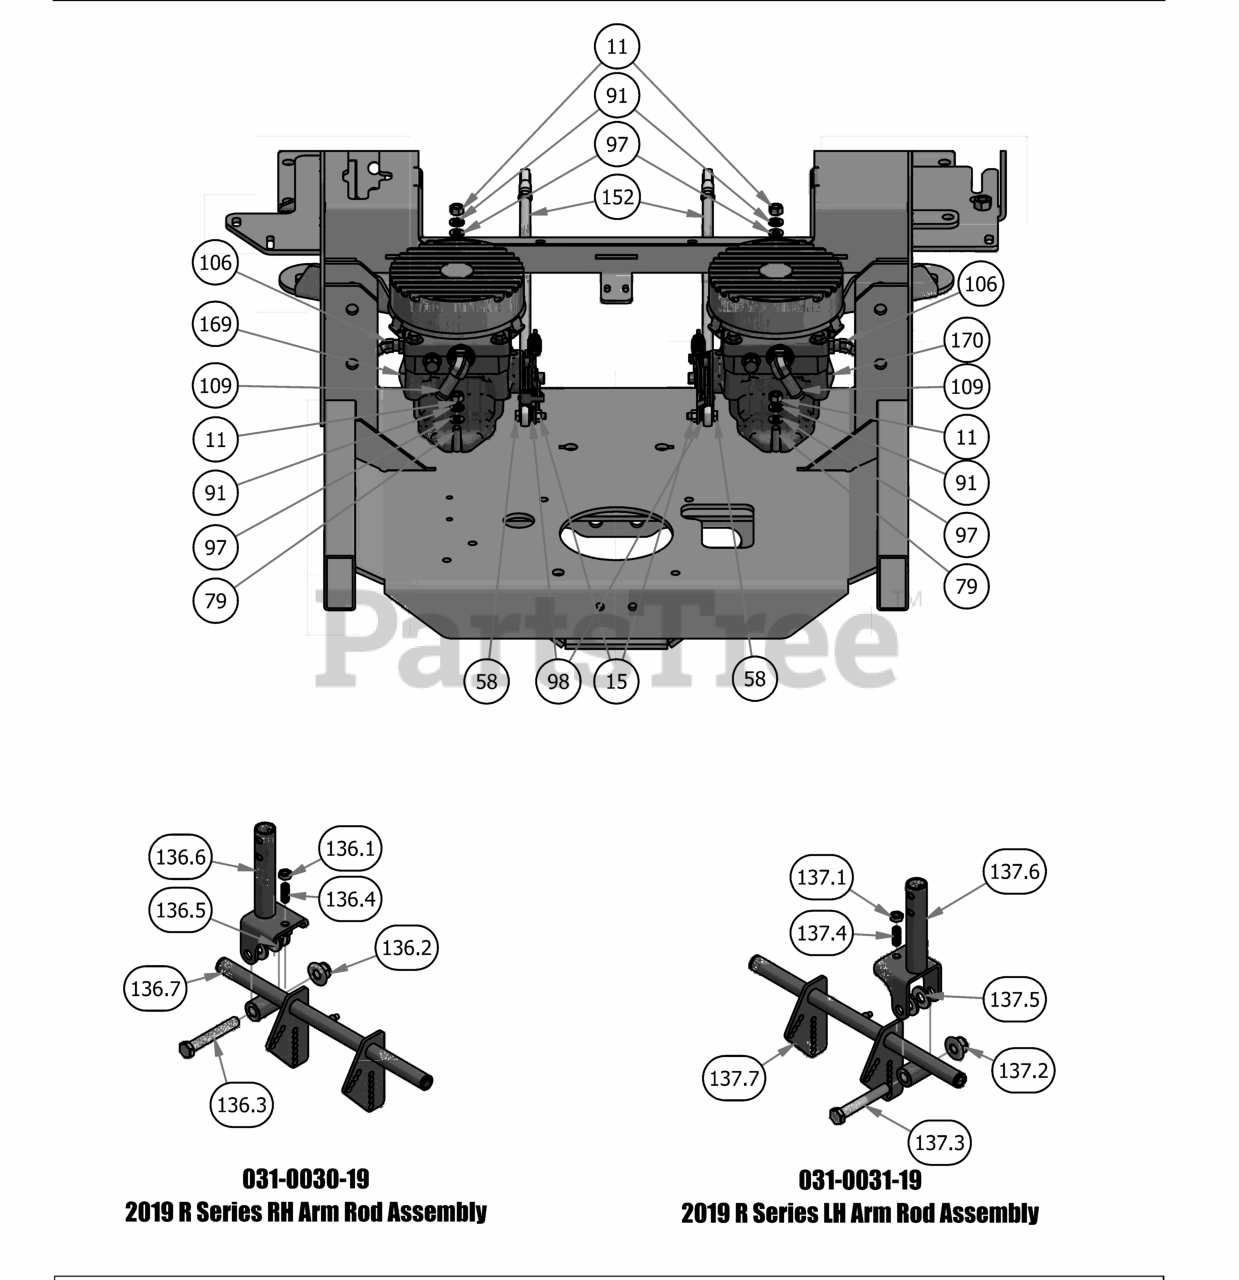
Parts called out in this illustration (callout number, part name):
11	3/8" Hex Nut
15	5/16" Nut
58	5/16 x 1 1/4 Hex Bolt
79	3/8 x 1.5" Bolt
91	3/8" Lock Washer
97	5/16" Flat Washer
98	5/16" Lock Washer
106	ZT Fitting, 3/8 x 3/8 45 Degree, 4603-6-6
109	90 Degree Fitting, 1/2 x 3/4, 4601-8-8
136.1	3/8-16 Half Jam Nut
136.2	1/2-13 Nylon Flange Nut
136.3	1/2-13 x 3.25 GR 5 Hex Bolt Zinc
136.4	3/8-16 x 1 Set Socket Set Screw Cup Point
136.5	.505 Nylon Spacer
136.6	Drive Arm Pivot
136.7	2019 Drive Arm Actuator right
137.1	3/8-16 Half Jam Nut
137.2	1/2-13 Nylon Flange Nut
137.3	1/2-13 x 3.25 GR 5 Hex Bolt Zinc
137.4	3/8-16 x 1 Set Socket Set Screw Cup Point
137.5	.505 Nylon Spacer
137.6	Drive Arm Pivot
137.7	2019 Drive Arm Actuator left
152	2019 Outlaw Gen2 XP Push Rod Assembly
169	2019 Rogue/Renegade Left Pump 16cc
170	2019 Rogue/Renegade Right Pump 16cc
